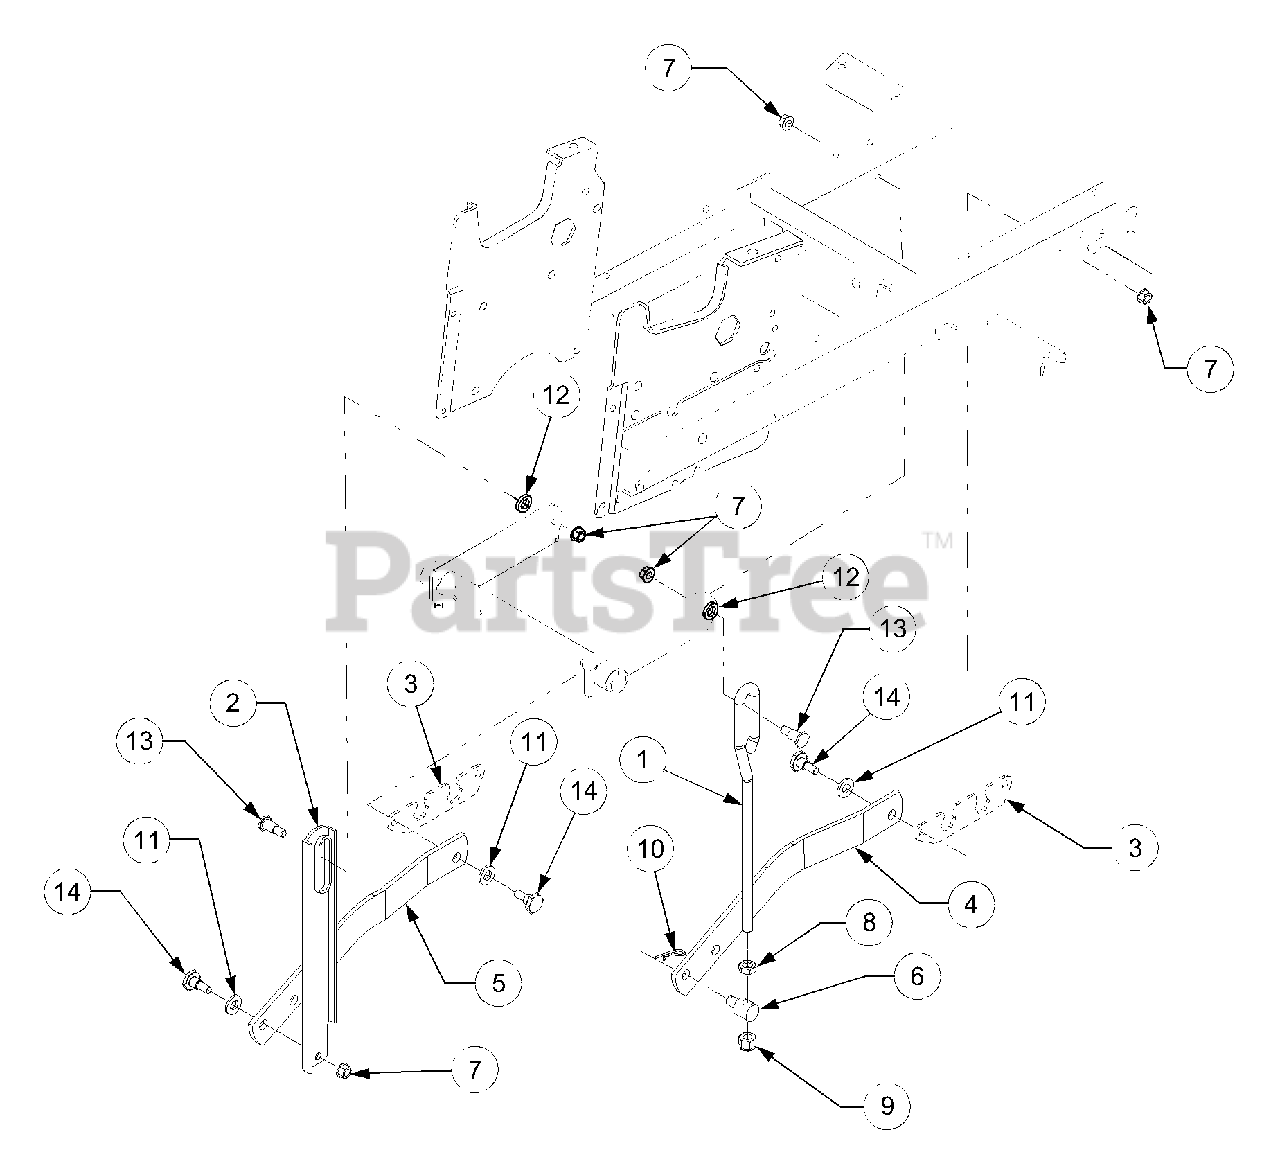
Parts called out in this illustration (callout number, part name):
1	Rod, Lift Link
7	Nut, Hex Flange Lock, 3/8-16
8	Nut, Hex Jam, 1/2-13 GR5
9	Nut, Hex Insert Lock, 1/2-13
10	Pin, Internal Cotter
11	Washer, Flat, .5 x 1.5 x .15
12	Washer, Flat, .531 x .875 x .15
13	Bolt, Shoulder
14	Bolt, Shoulder
